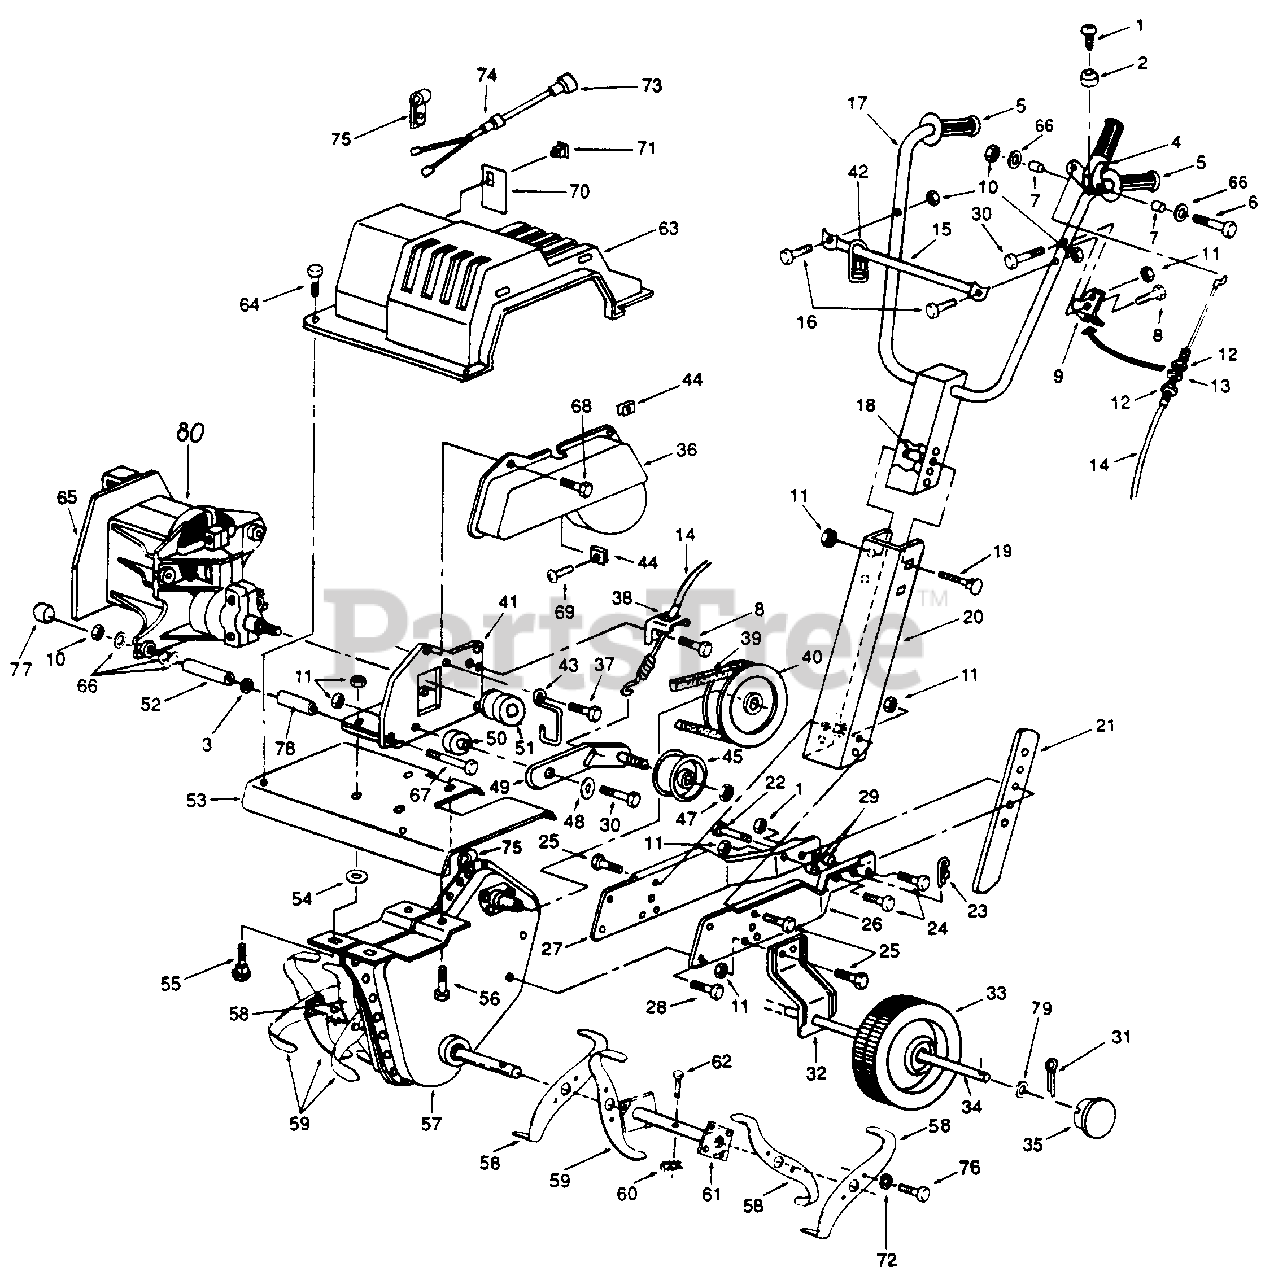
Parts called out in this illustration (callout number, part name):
1	Tap. Screw #10-16 x 1/2
2	Rubber Bumper
3	Spacer
4	Clutch LeverAssembly
5	HandleGrip
6	Hex Bolt 1/4-20 x 2
7	Spacer
8	Hex Tap. Scr. 1/4-14 x 1/2
9	Cable Bracket
10	Lock Nut 1/4-20
11	Lock Nut 5/16-18
12	Hex Jam Nut 5/16-24
13	Lock Washer 5/16 Spring
14	Clutch Control Cable
15	Bar-Cord Control
16	Hex Bolt 1/4-20 x 1-1/4
17	Handle Assembly
18	Spacer
19	Carr. Bolt 5/16-18 x 2-1/4
20	Handle Channel - Frame
21	Depth Stake
22	Clevis Pin
23	Hair Pin coner
24	Hex Bolt 5/16-18 x 1
25	Hex Bolt 5/16-18 x 5/8
26	LH Frame Ha
27	RH Frame Han
28	Hex Tap. Scr. 5/16-18 x 1/2
29	Spacer
30	Hex Bolt 5/16-18 x 1-1/4
31	coner Pin
32	Wheel Bracket
33	Wheel - 6
34	Axle - Wheel
35	Hub Cap
36	Belt Cover
37	Hex Bolt 1/4-20 x 5/8
38	Bracket-Clutch Lever
39	V-Belt
40	Pulley-Chain Case
41	Plate-Motor Mounting
42	Cord Minder
43	Belt Retainer
44	Clip-Tinnerrnan
45	Flat Idler Pulley
47	Lock Nut 3/8-24 Hex Jam
48	Flatwasher 5/16
49	Idler Arm Assembly
50	Pivot Spacer
51	Motor Pulley
52	Spacer
53	Tine Shieb (Red)
54	Spacer
55	Carriage Bolt 5/16-18 x 1
56	Hex Bolt 5/16-1 8 x 3/4
57	Chain Case Ass'y Complet
58	RH Tine Blade
59	LH Tine Blade
60	Hair Pin coner
61	Adaptor Assembly-Tine
62	Clevis Pin
63	Motor Cover
64	Tapping Screw #10 x 1/2
65	Air Battle
66	Flatwasher 1/4
67	Hex Bolt 1/4-20 x 3-1/4 Grade 5
68	Nybn Screw 1/4-20 x 1/2
69	Screw #10-24 x 1/2 Sems
70	Decal- Rating
72	Lock Washer 1/4 Spring
73	Plug Assembly
74	Strain Reliet - Heyco
75	Cord Clamp
76	Screw 1/4-20 x 1/2
77	End Cap Insulator
78	Spacer Insulator
79	Flat Washer 3/8
80	Motor Ass'y Complete
